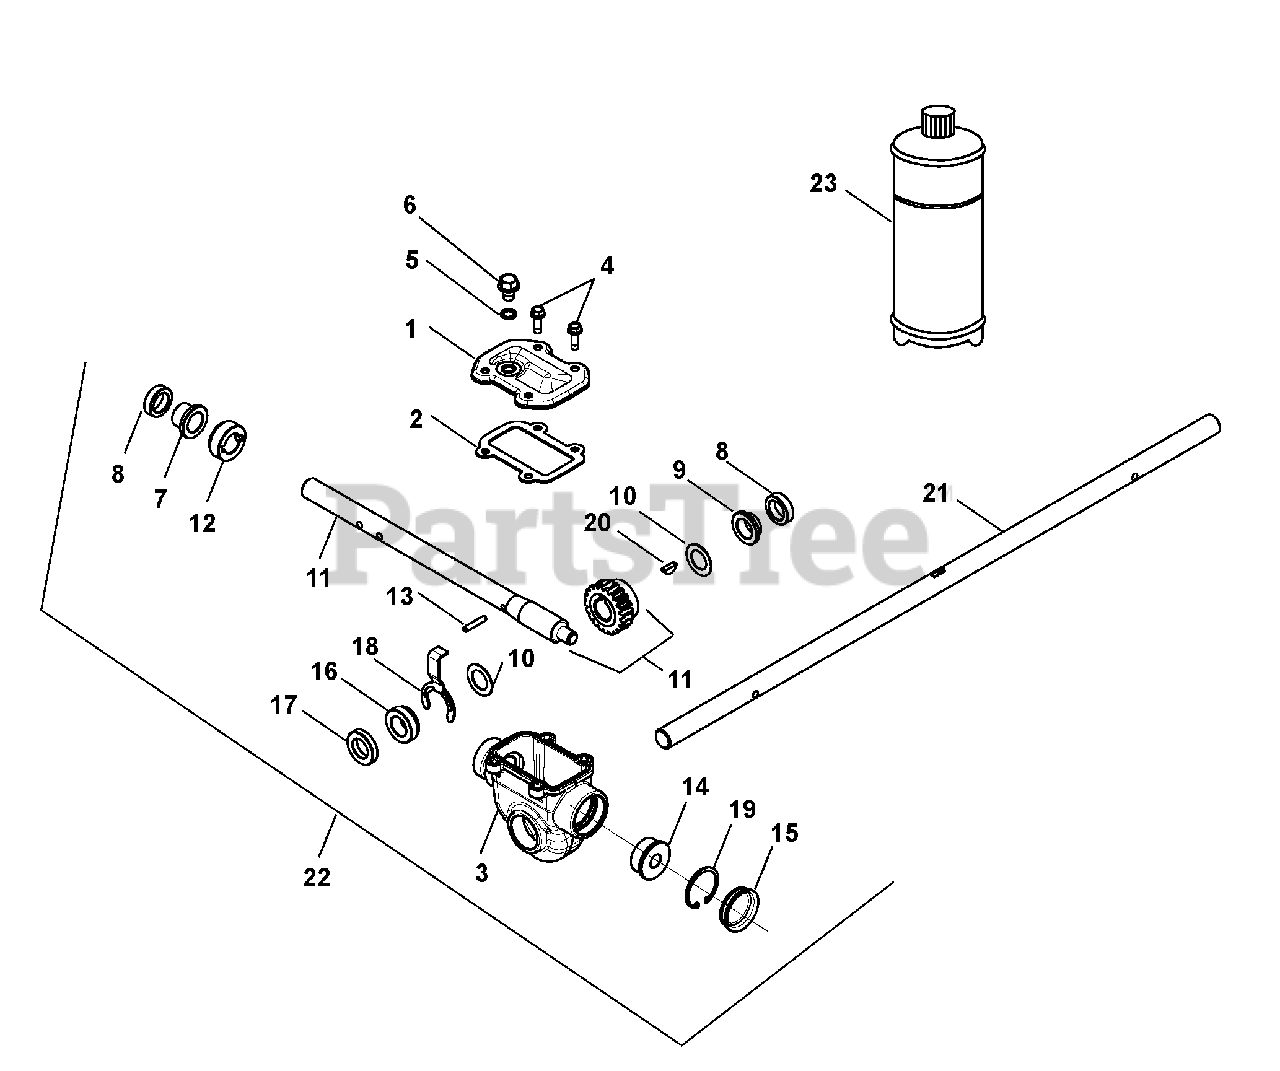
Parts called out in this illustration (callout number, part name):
1	COVER, TOP - COMPACT
2	GASKET, TOP - COMPACT GEARCASE
3	GEARCASE, COMPACT ALUMINUM
4	SCR-TAP .25-20X.75 HWH TR YWZ
5	WSHR-BND-SEAL .38X.75X.11 GALV
6	@SCR-ROLOK .38-16X.50 HWH YWZC
7	BSHG-FLG .755X.878X.75X1.25
8	SEAL-OIL .748X1.125X.312 TBC29
9	BSHG-FLG .755X.878X.424X1.25
10	WSHR-FL-STL .760X1.225X.032 YZ
11	SHAFT AND WORM GEAR ASSEMBLY
12	THRUST COLLAR, .75" ID SLIPFIT
13	PIN-STR .188X1.00 6150
14	BSHG-FLG .503X1.303X.62X1.465
15	COVER, GEAR CASE 1.50"
16	BSHG-FLG COMPACT, RIGHT
17	SEAL-OIL .748X1.300X.250 TBC29
18	BUSHING RETAINER, COMPACT
19	RG-RTNG-INT 1.500X.050
20	KEY-WDRF .19X.63 HRD #61
21	SHAFT, RAKE-28" (.750 DIA)
21	SHAFT, RAKE - 22" (.750 DIA)
21	SHAFT, RAKE - 24" (.750 DIA)
21	SHAFT, RAKE - 20" (.750 DIA)
22	GEAR CASE, 24" ALUM SM TOP-LD
22	GEAR CASE, 22" ALUM SM TOP-LD
22	GEAR CASE, 28" ALUM SM TOP-LD
22	GEAR CASE, 20" ALUM SM TOP-LD
23	ARIENS L3 LUBE, 8 OZ BOTTLE
